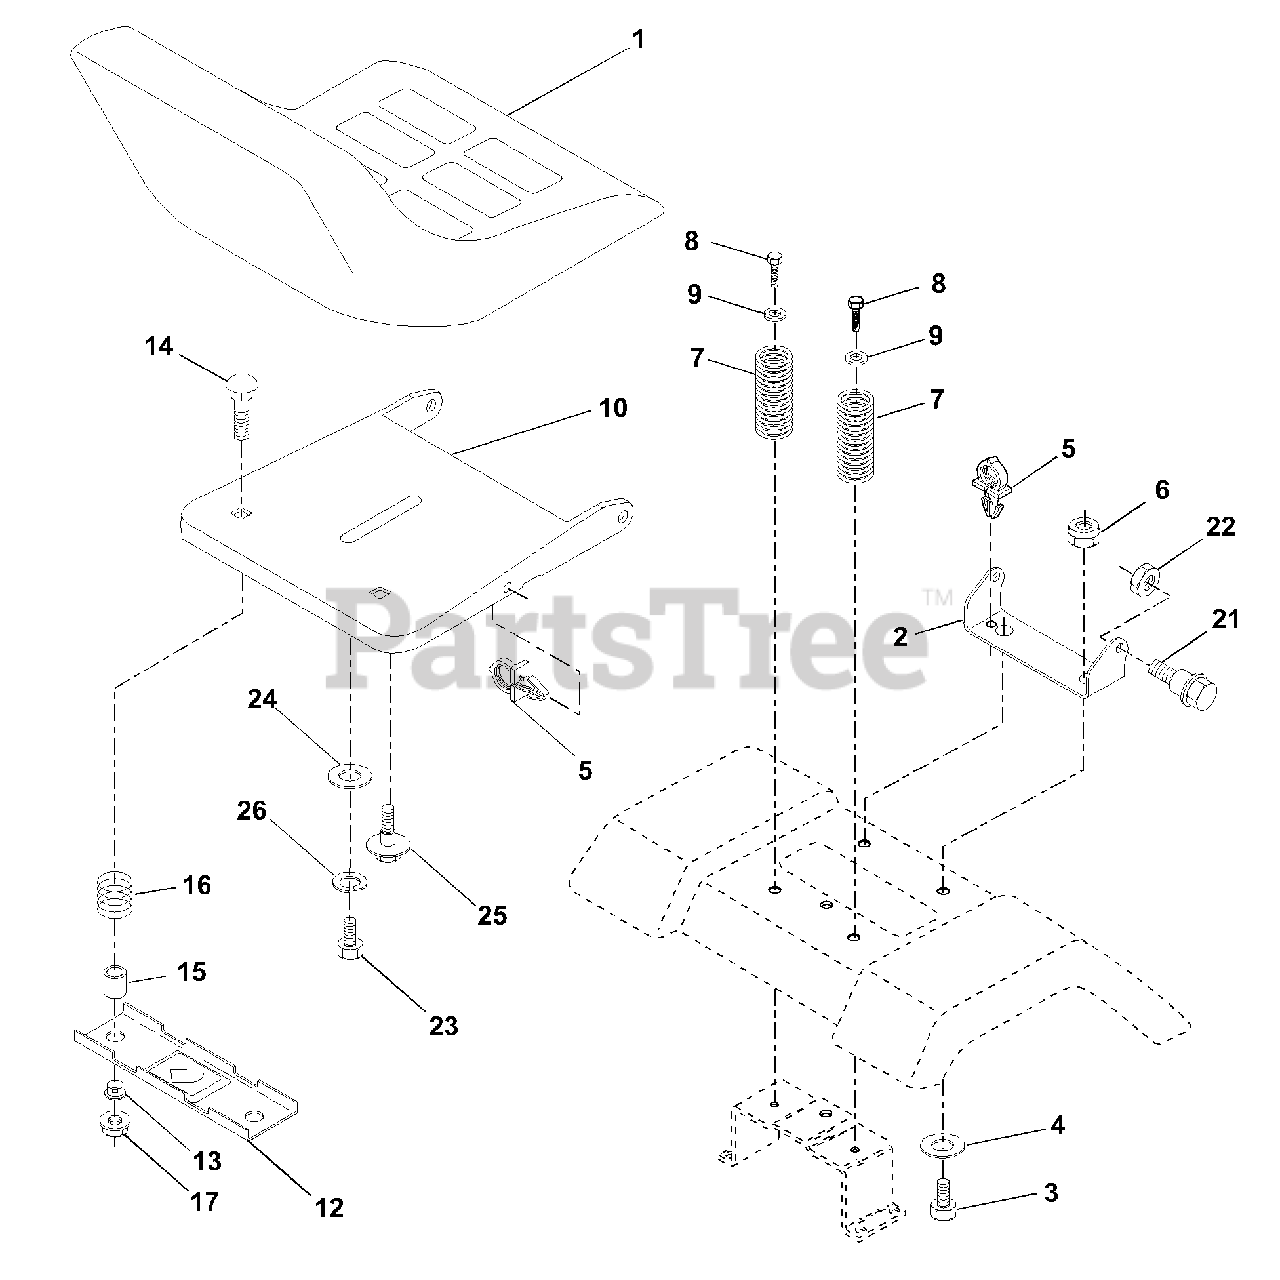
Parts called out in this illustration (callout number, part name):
1	Seat
2	Bracket Pivot Seat 8 720
3	Bolt Fin Hex 3/8-16unc X 1
4	Washer 13/32 X 1 X 10 Ga
5	Clip Push-In
6	Nut Hex w/Ins. 3/8-16 Unc
7	Spring Seat Cprsn 2 250 Blk Zi
8	Screw 3/8-16 X 1
9	Washer 13/32 X 1 X 14 Ga.
10	Pan Seat
12	Bracket Mounting Switch
13	Bushing Snap Blk Nyl 50 Id
14	Bolt Rdhd Sqnk 1/4-20x1-1/2
15	Spacer Split 28x 96 Yel Zinc
16	Spring Cprsn 1 27 Blk Pnt
17	Nut Lock 1/4 Lge Flg Gr 5 Zinc
21	Bolt Shoulder 5/16-18 Unc-2A
22	Nut Hex Lock W/Ins 5/16-18
23	Bolt, Hex Black
24	Washer 17/32 X 1-3/16 X 12 Ga.
25	Bolt Shoulder 5/16-18 X 62
26	Washer Lock
